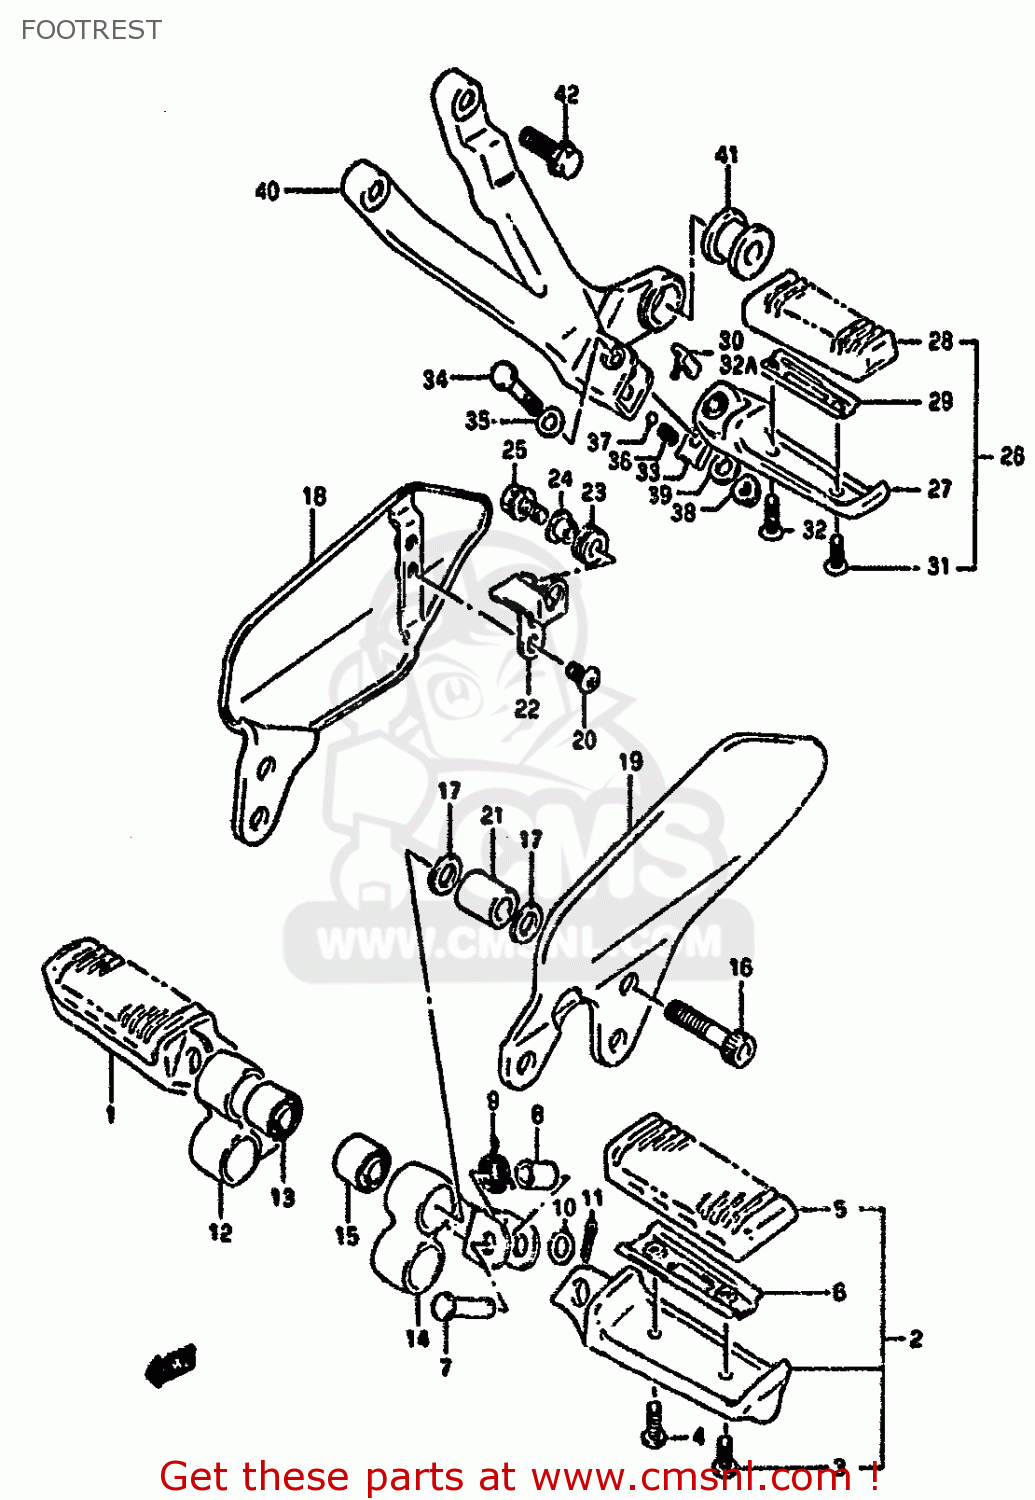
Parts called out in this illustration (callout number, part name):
1	FOOTREST ASSY,FR,R
2	FOOTREST ASSY,FR,L
3	SCREW
4	SCREW
5	RUBBER,FOOTREST
6	PLATE,FR FOOTREST RUBBER
7	PIN
8	SPACER(8.1X12X22)
9	SPRING
10	WASHER
11	PIN 20X20
12	HOLDER,FRONT FOOTREST
13	BUSH
14	HOLDER COMP,FRONT FOOT
15	BUSH
16	BOLT
17	WASHER
18	GUARD,FRONT FOOTREST,RIGHT
19	FOOT GUARD,LH
20	SCREW
21	SPACER,FRONT FOOTREST
22	PLATE,FRONT FOOTREST GUARD
23	CUSHION
24	WASHER
25	BOLT
26	FOOTREST ASSY,PILLION,R
27	BAR COMP,PILLION FOOTREST
28	RUBBER,RR FOOTREST
29	PLATE,RUBBER STOPPER
30	CUSHION,PILLION FOOTREST
31	SCREW
32	SCREW 5X16
32A	CUSHION,PILLION FOOTREST
33	PLATE,SPRING STOP,R
34	BOLT(6X45)
35	SHIM(8.2X22X0.2)
36	SPRING
37	BALL
38	NUT
39	WASHER
40	BRACKET,PILLION FOOTREST
41	BUSH(10.2X25X19)
42	BOLT
